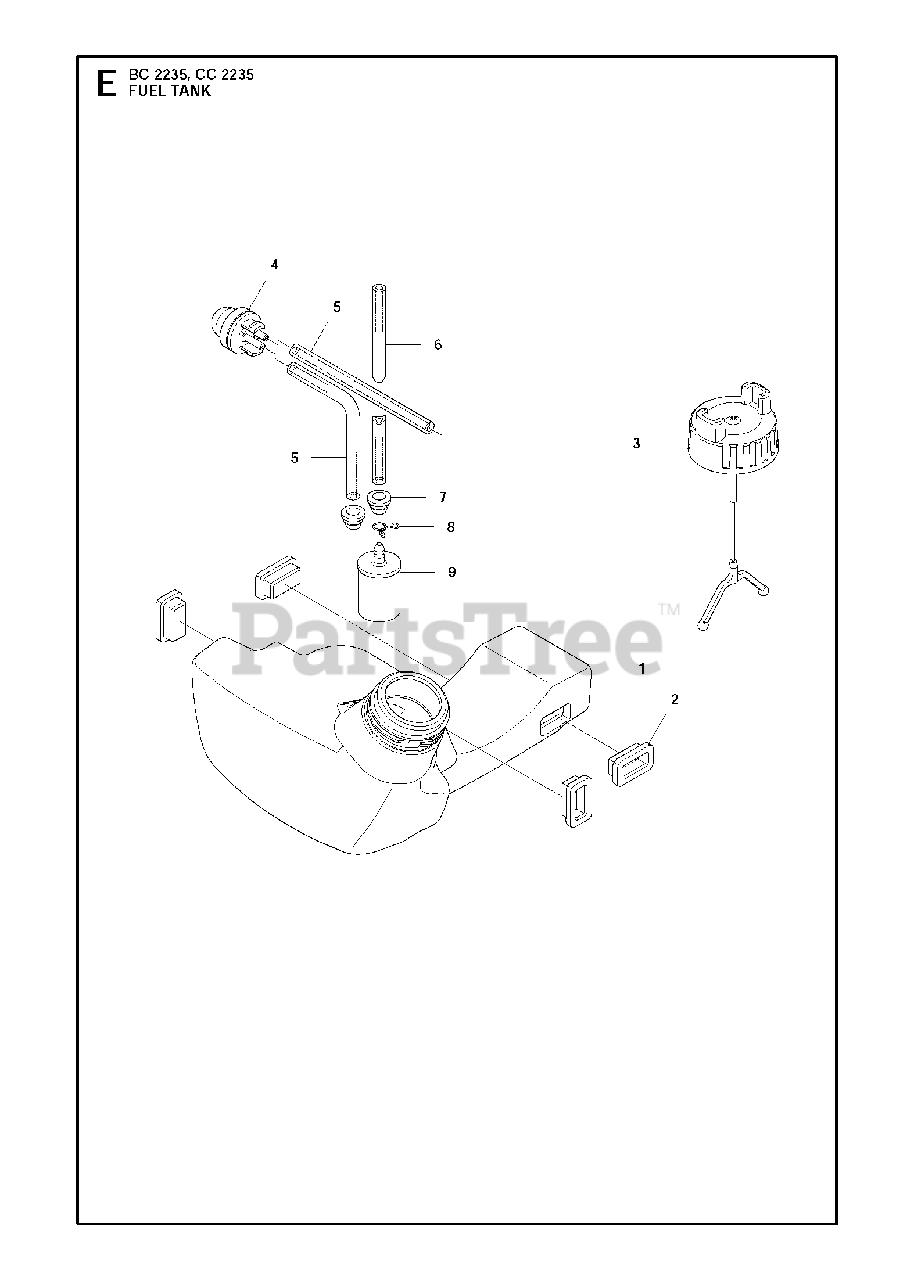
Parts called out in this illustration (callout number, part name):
1	TANK ASSY
4	AIR PURGE BUBBLE
7	FUEL TANK BUSHING
9	FUEL FILTER
